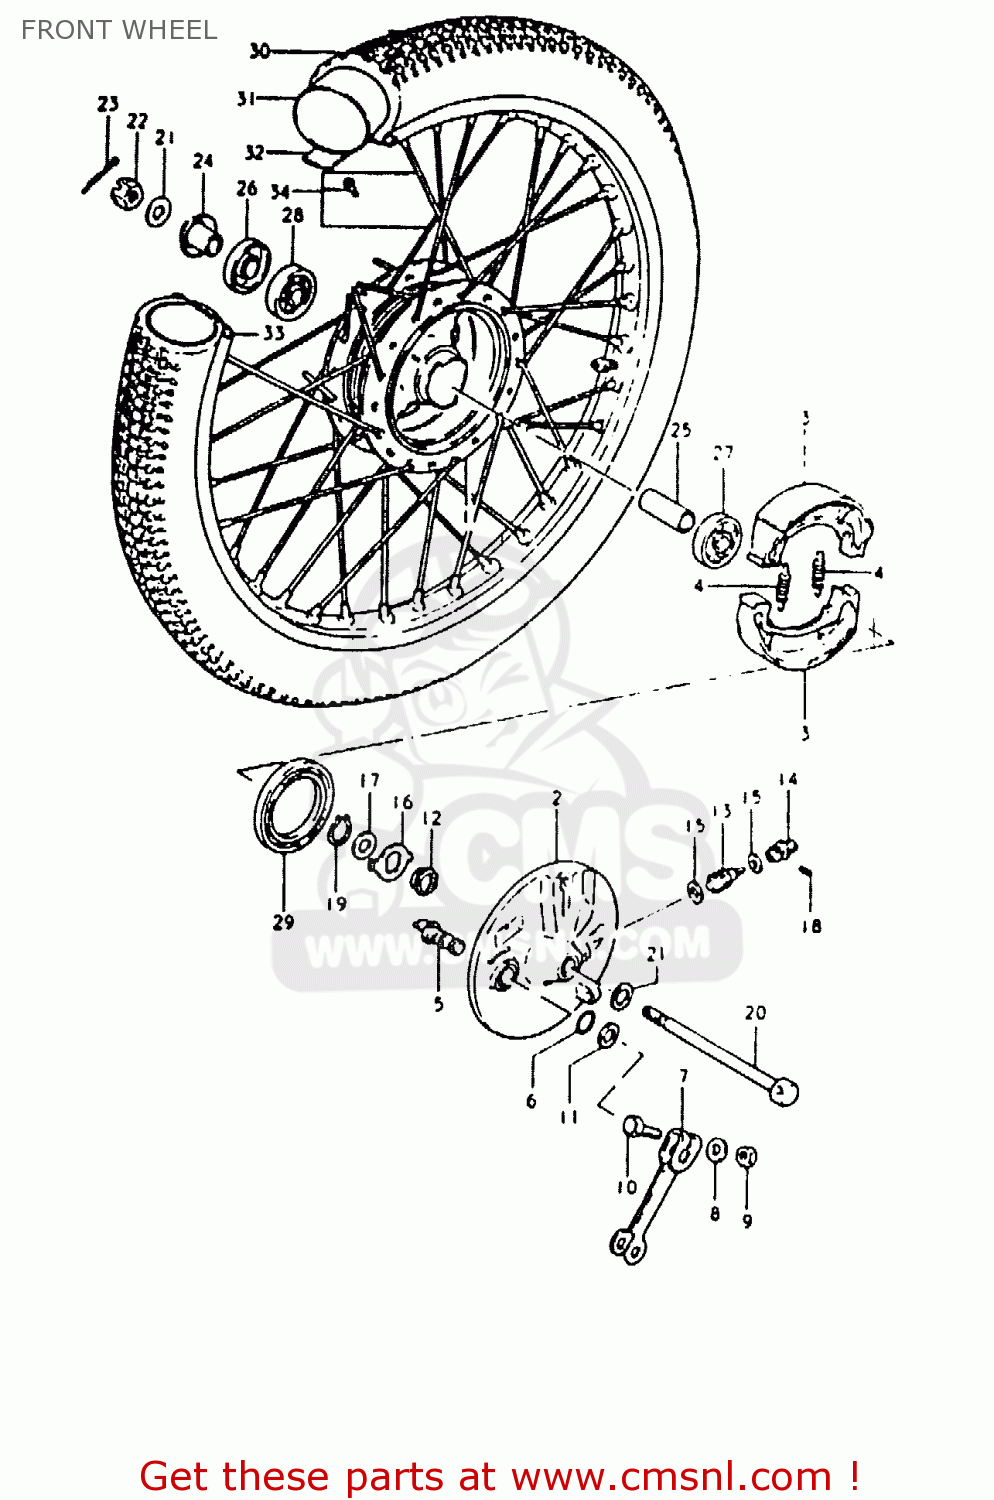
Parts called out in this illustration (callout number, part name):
1	HUB,FRONT
2	PANEL, FRONT HUB
3	SHOE,BRAKE
4	SPRING(L:34)
5	CAM,FRONT BRAKE
6	O-RING (D:2.4 ID:13.8)
7	LEVER,FR BRAKE CAM
8	WASHER
9	NUT
10	BOLT(6X33)
11	WASHER (14.5X22X1.6)
12	GEAR,SPEEDOMETER
13	PINION,SPEEDOMETER
14	BUSH,METER GEAR OUTER
15	WASHER (5.1X9X0.4)
16	DRIVER,SPEEDOMETER GEAR
17	WASHER(18.5X24X1)
18	SCREW
19	CIRCLIP
20	AXLE,FRONT
21	WASHER
22	NUT
23	PIN 20X20
24	SPACER,FRONT AXLE,RIGHT
25	SPACER (10.2X16X51)
26	SEAL,OIL(15X31X5)
27	BEARING
28	BEARING
29	OIL SEAL (43X58X7)
30	TIRE,FRONT
31	TUBE
32	PROTECTOR,WHEEL,INNER
33	RIM, WHEEL
34	SPOKE ASSY
